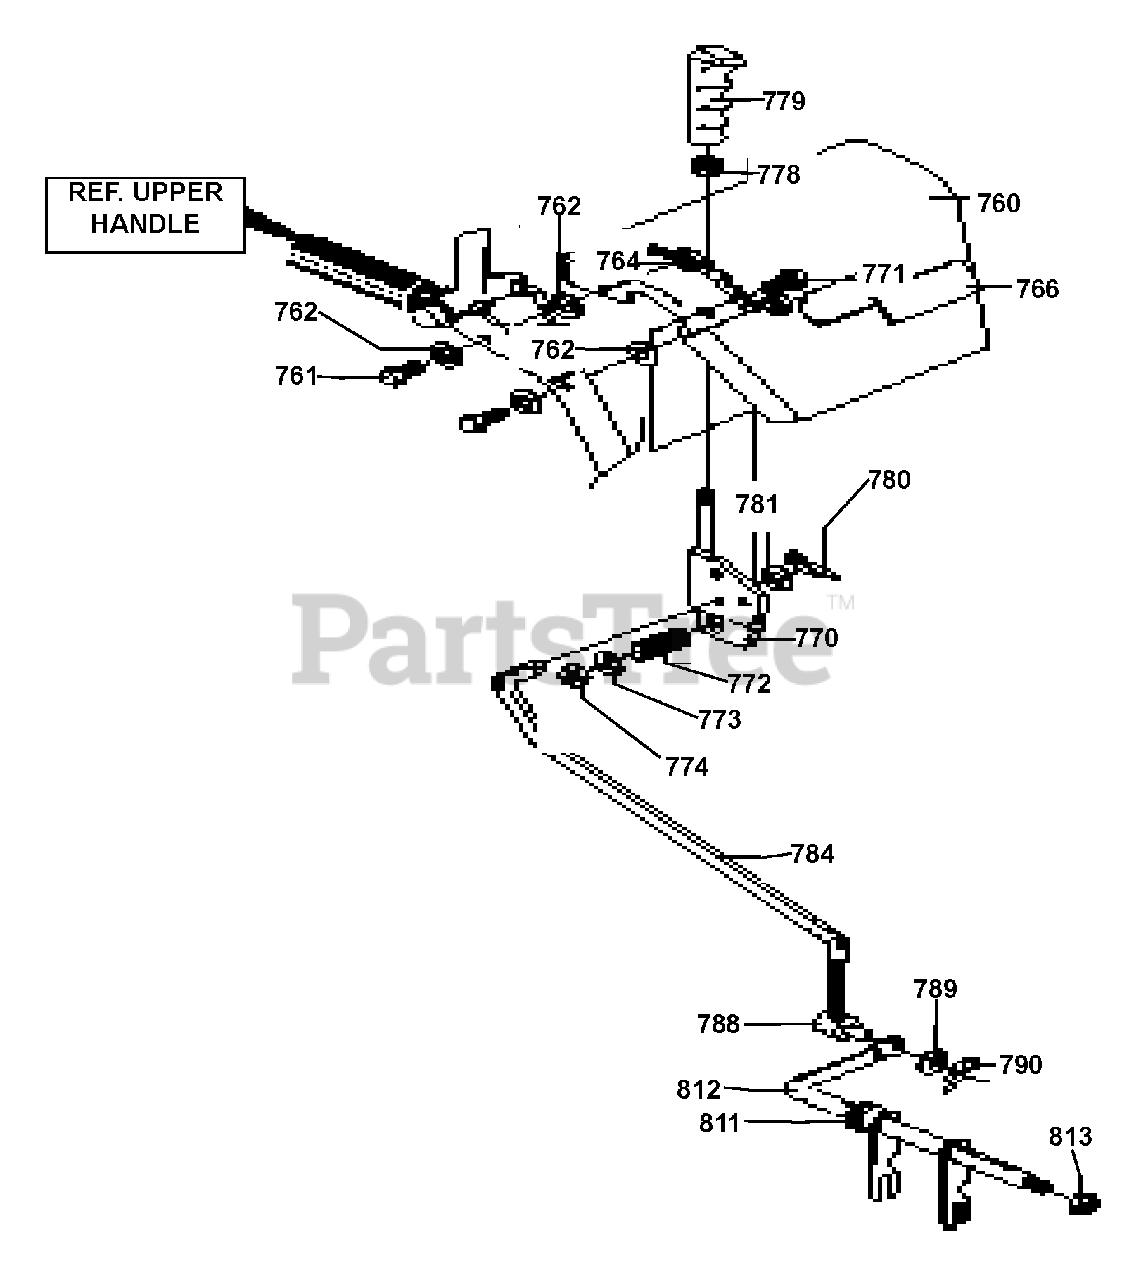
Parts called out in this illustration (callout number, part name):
754	SCREW, 5/16-18X .75
760	ASSY, PANEL
761	SCREW 5/16-18X1.75
762	FLATWASHER
764	NUT 5/16-18 HEXWDFLLK
766	PLATE, PANEL
770	HANDLE ASSY SPD CTRL
771	SCREW 3/8-16X2.00
773	FLATWASHER
774	NUT, 3/8-16 HEXNYL
778	NUT, 3/8-16RGHXCTRLK
779	HANDLE 3/8-16
780	PIN, COTTER
781	FLATWASHER
784	ROD, SPEED CONTROL
788	NUT, TRUNNION
789	FLATWASHER
790	COTTER PIN
811	BEARING, FLANGE
812	ROD, ASSY YOKE
813	NUT, 3/8-16RGHXCTRLK
